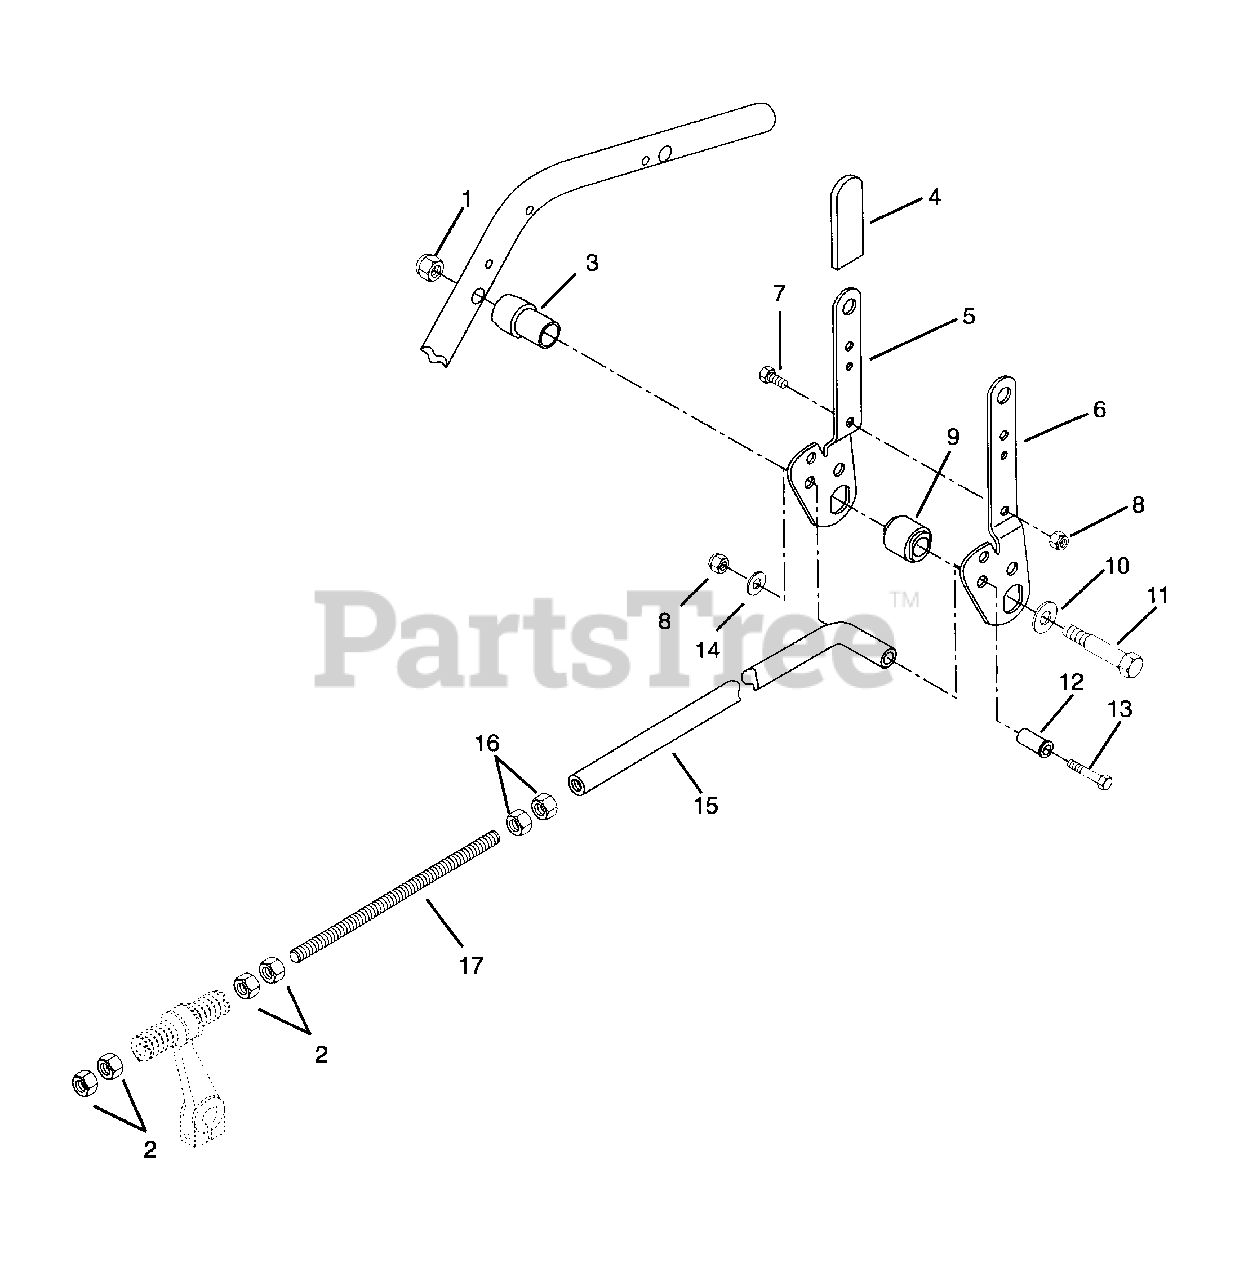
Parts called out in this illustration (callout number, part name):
1	Nut-Locking-Center .375-16 Grade 2
2	Nut-Jam .375-16
3	Pivot, Hand Lever Left Hand
4	Grip, Handle
5	Handle, Control Right Hand
6	Handle, Control Left Hand
7	Bolt-Hex .25-20 x .63
8	Nut-Locking-Center .250-20 Grade 2
9	Bushing Flange .751 x 1.13 x 1.07
10	Washer-Flat-Steel .531 x 1.062 x .095
11	Bolt-Hex .38-16 x 3.5
12	Bushing-Flange .257 x .38 x 1.080
13	Bolt-Hex .25-20 x 1.50 Grade 5
14	Washer-Flat-Steel .281 x .620 x .065
15	Rod, Control Hi-Lo
16	Nut-Hex .375-16 Grade 2
17	Rod, Extension
